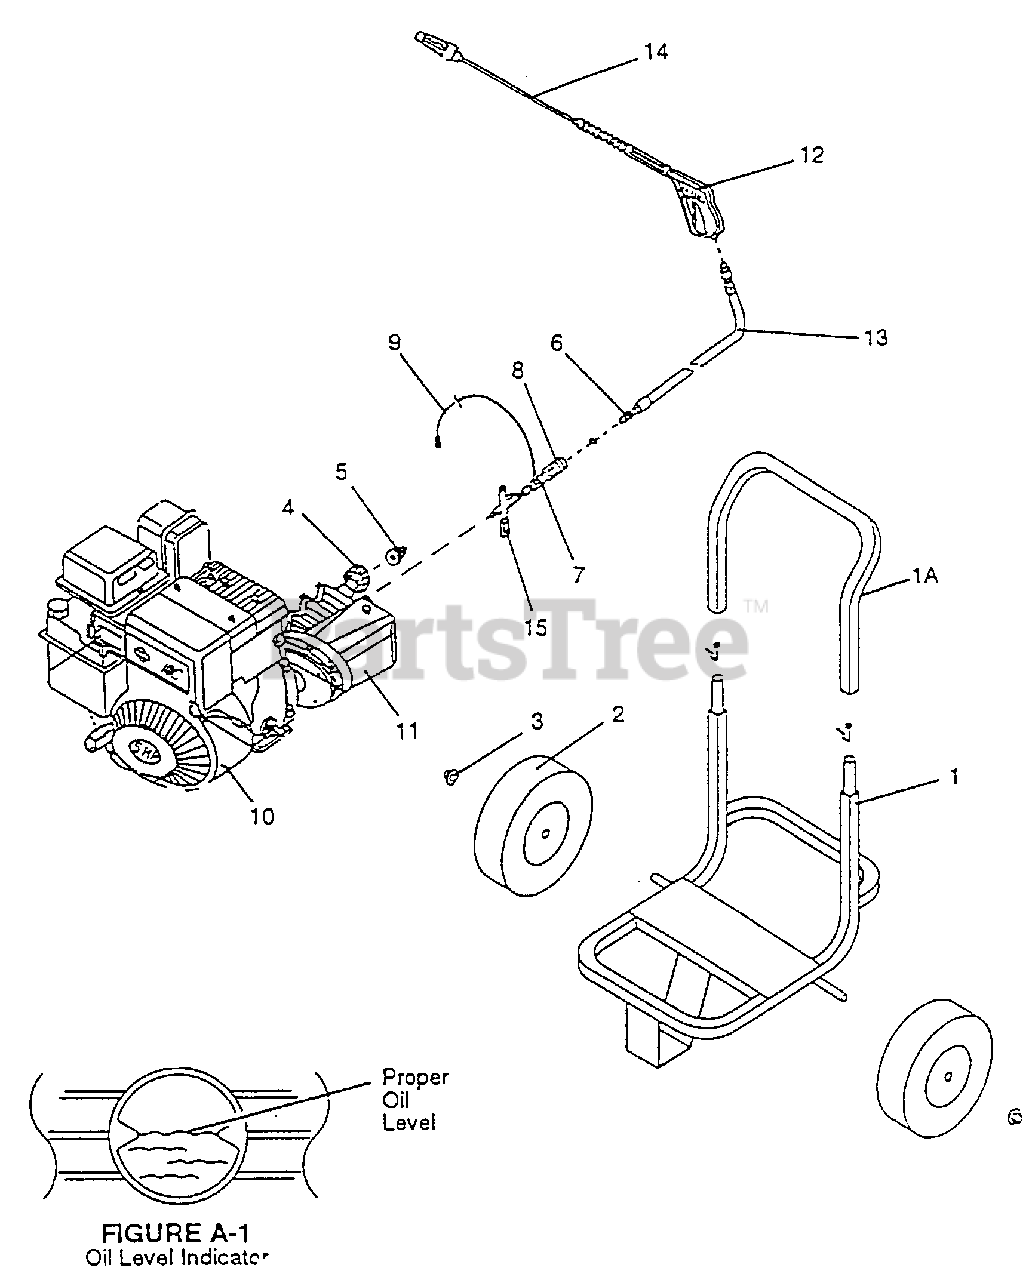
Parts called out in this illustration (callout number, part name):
1A	Handle Bar
2	Hard Rubber Tires
3	Hub Caps
4	Garden Hose - Nut, Adapter
5	Hose Screen
6	3/8" Q.C. Plug
7	Downstream Injector - Low PSI
8	Q.C. Female Socket - 3/8"
9	Chemical Syphon Hose w/Chemical Screen
10	5 HP Briggs & Stratton Engine
12	Trigger Gun w/Wand
13	Hose R1 3/8" x 25'
14	Multi Reg Nozzle w/12" Extension
15	Unloader Valve
